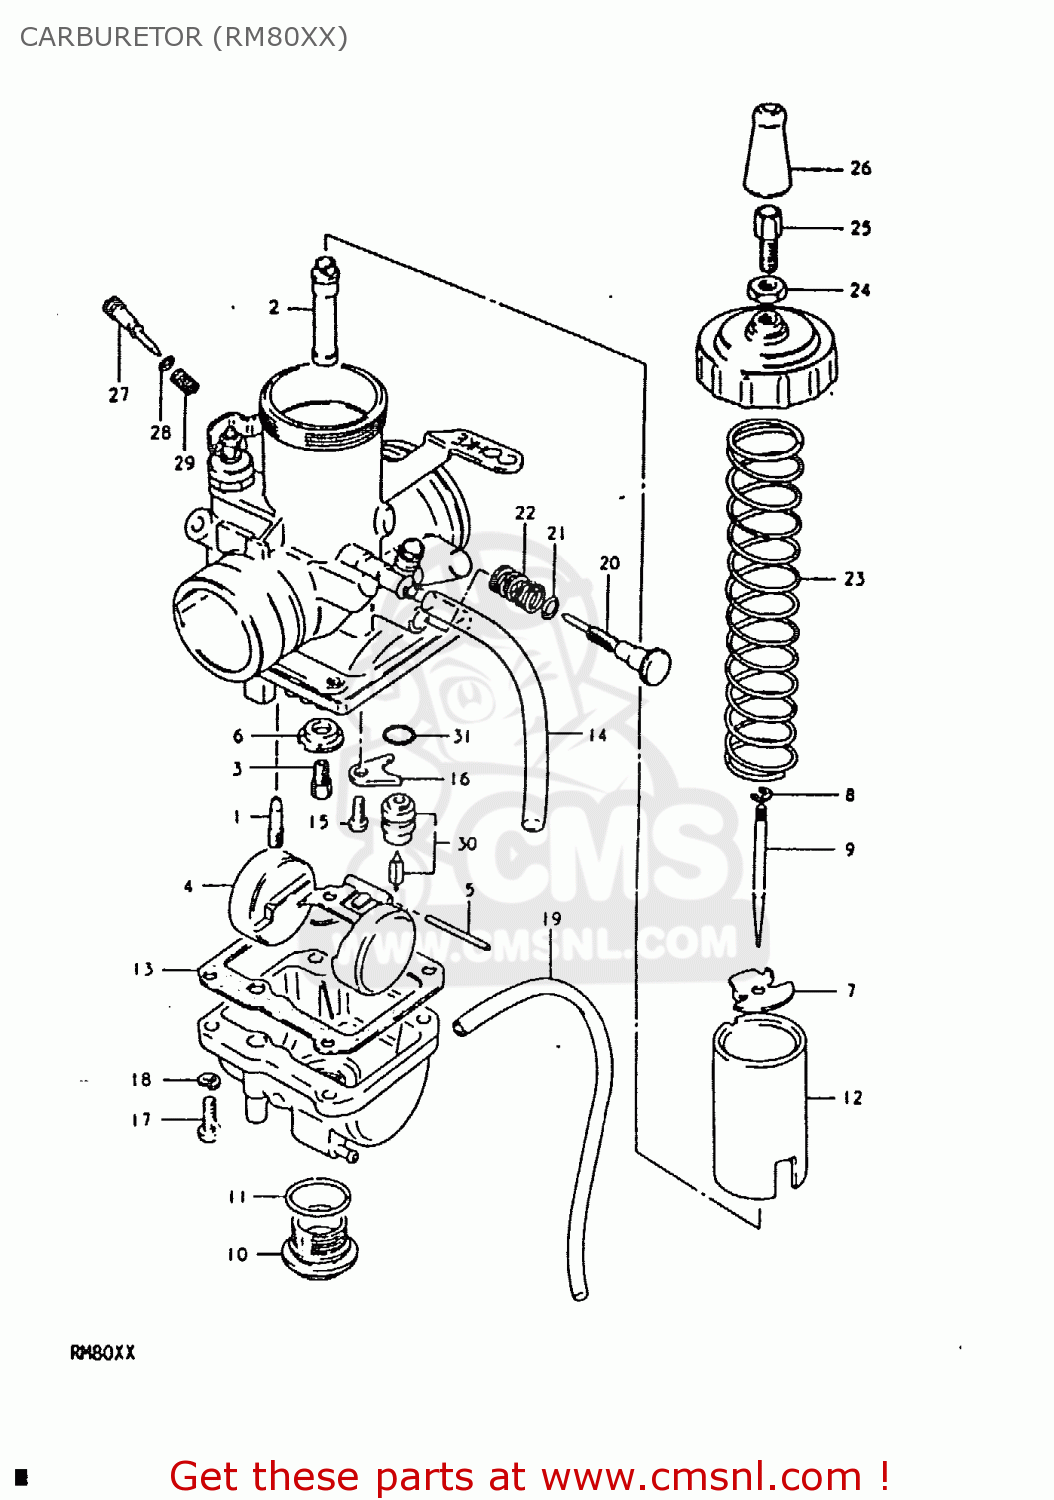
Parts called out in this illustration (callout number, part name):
1	JET,PILOT(35)
2	JET,NEEDLE
3	JET,MAIN(145)
4	FLOAT
5	PIN,FLOAT
6	RING
7	PLATE,THROTTLE VALVE
8	CLIP
9	NEEDLE,JET(5DP39-4)
10	PLUG
11	O RING
12	VALVE,THROTTLE
13	GASKET,FLOAT CHAMBER (NAS)
14	HOSE
15	SCREW
16	PLATE
17	SCREW
18	LOCK WASHER
19	HOSE, AIR VENT (3*5*200)
20	ADJUSTER
21	O-RING
22	SPRING
23	SPRING,THROTTLE VALVE
24	NUT
25	ADJUSTER,CABLE
26	CAP
27	SCREW,PILOT AIR ADJUSTING
28	O RING
29	SPRING
30	VALVE ASSEMBLY,NEEDLE
31	O RING
